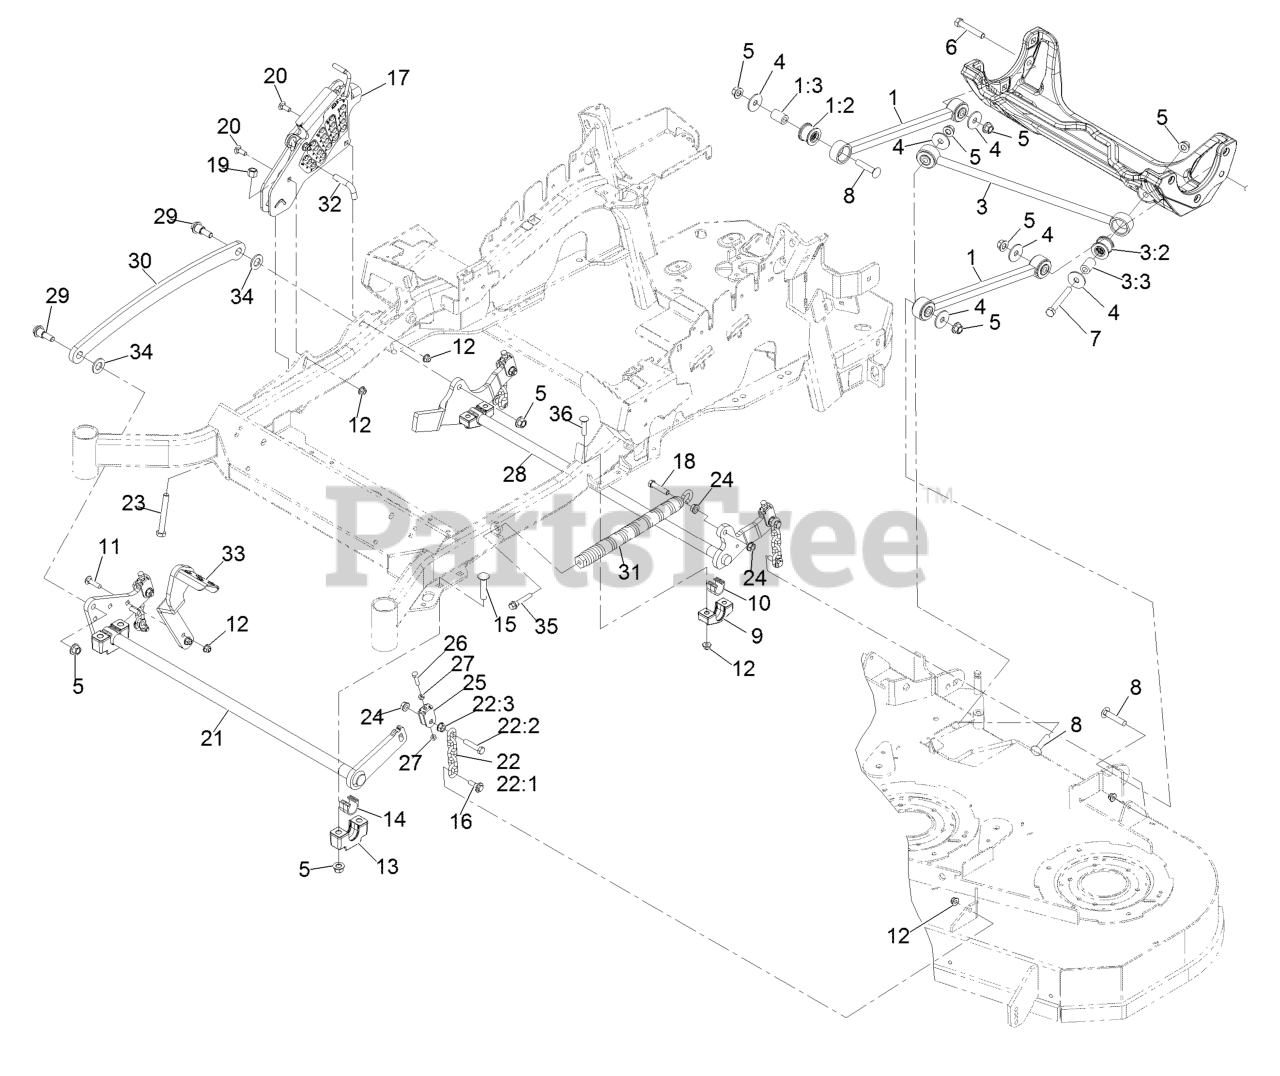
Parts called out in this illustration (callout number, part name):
1	LONG STRUT ASM
1:2	BUSHING-SUSPENSION, RUBBER
3	PANHARD ROD ASM
3:2	BUSHING-SUSPENSION, RUBBER
4	WASHER-THRUST
5	Nut-Lock 1/2-13
6	SCREW-HH
7	SCREW-HH
8	SCREW-CARR
9	SUPPORT-CROSS SHAFT, BEARING REAR
10	BEARING-CROSS SHAFT, REAR
11	SCREW-CARR
12	NUT-HF, NI
13	SUPPORT-CROSS SHAFT, BEARING
14	BEARING-CROSS SHAFT, FRON
15	Bolt-Carriage 1/2-13 X 2 1/2 Spl Neck
16	SCREW-SHOULDER, HHF
17	HOC ASM
18	SCREW-HH
19	NUT-LOCK, NI
20	BOLT-CARR
21	DECKLIFT-FRONT
22	DECK LIFT CHAIN ASM
22:1	CHAIN-LIFT, DECK
22:2	SCREW-HH
23	BOLT-TAP
25	YOKE-ADJUST, DECK
26	SCREW-HH
27	NUT-JAM
28	LIFT-DECK, REAR
29	SCREW-SHOULDER, HHF 1/2-13 X 1.12
30	LINK-LIFT, DECK
31	SPRING-EXTENSION
32	PIN-HOC
33	LEVER-FOOT
34	WASHER-FLAT
35	BOLT-SHOULDER
36	Bolt-Carriage 3/8-16 X 2 1/4
